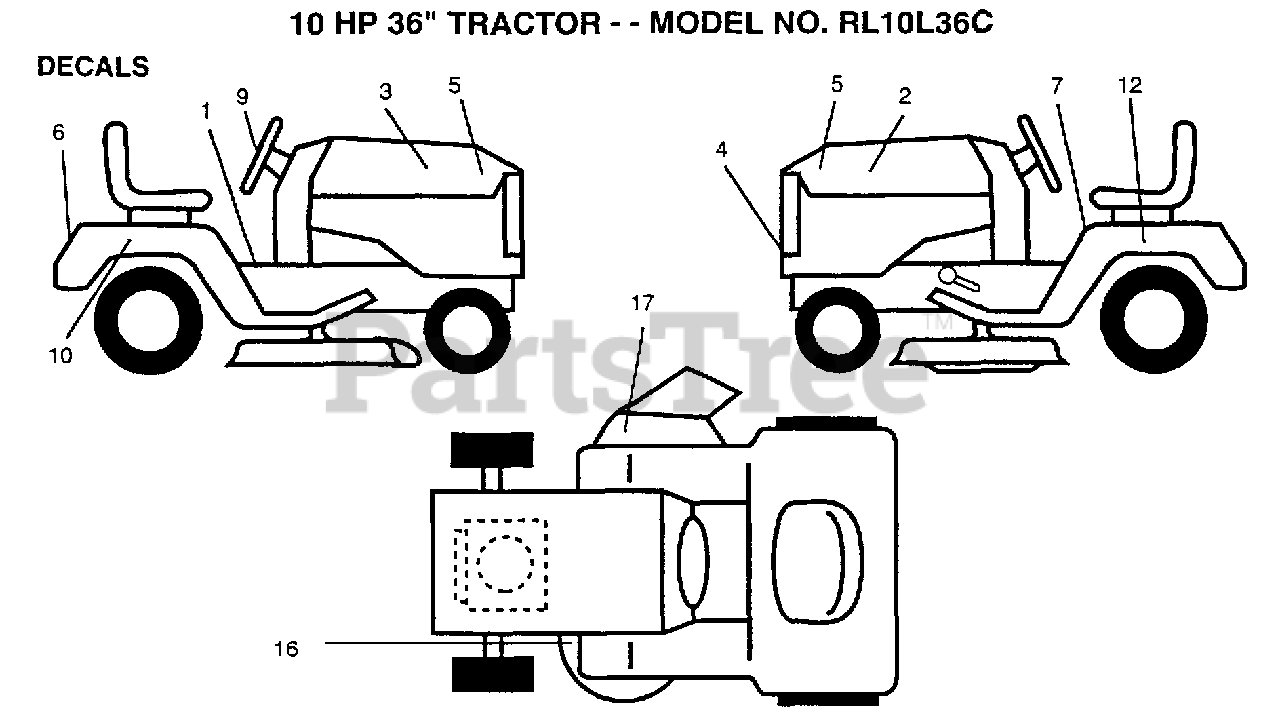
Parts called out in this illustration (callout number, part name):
1	DECAL.INST.OPER.
2	DECAL HD RLY LH
3	DECAL HD RLY RH
4	GRILL DECAL
6	FENDER DECAL
7	DECAL CAUTION
9	"DECAL,STR WHL"
10	DECAL.FEND.QUICKS
12	DECAL
16	"DECAL, WARNING"
17	DECAL.V.BELT
